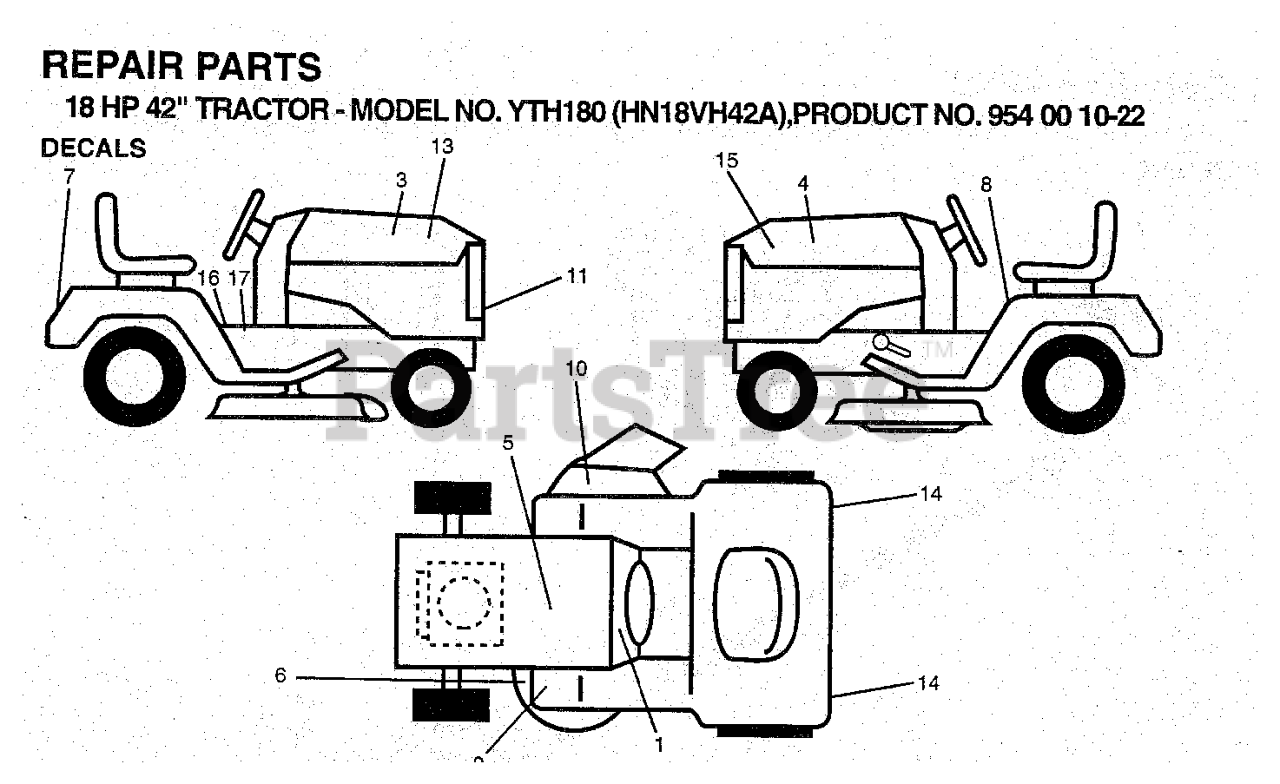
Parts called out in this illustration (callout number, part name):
3	DECAL
4	DECAL
7	DECAL FENDER NLA
8	DECAL CAUTION
10	DECAL WARNING (ENGLISH/FRENCH)
11	DECAL GRILL HUSQ NLA
13	DECAL-HOOD R.H.
14	REFLECTOR-TAIL YT
15	DECAL-HOOD L.H.
17	DECAL PARK BRAKE
